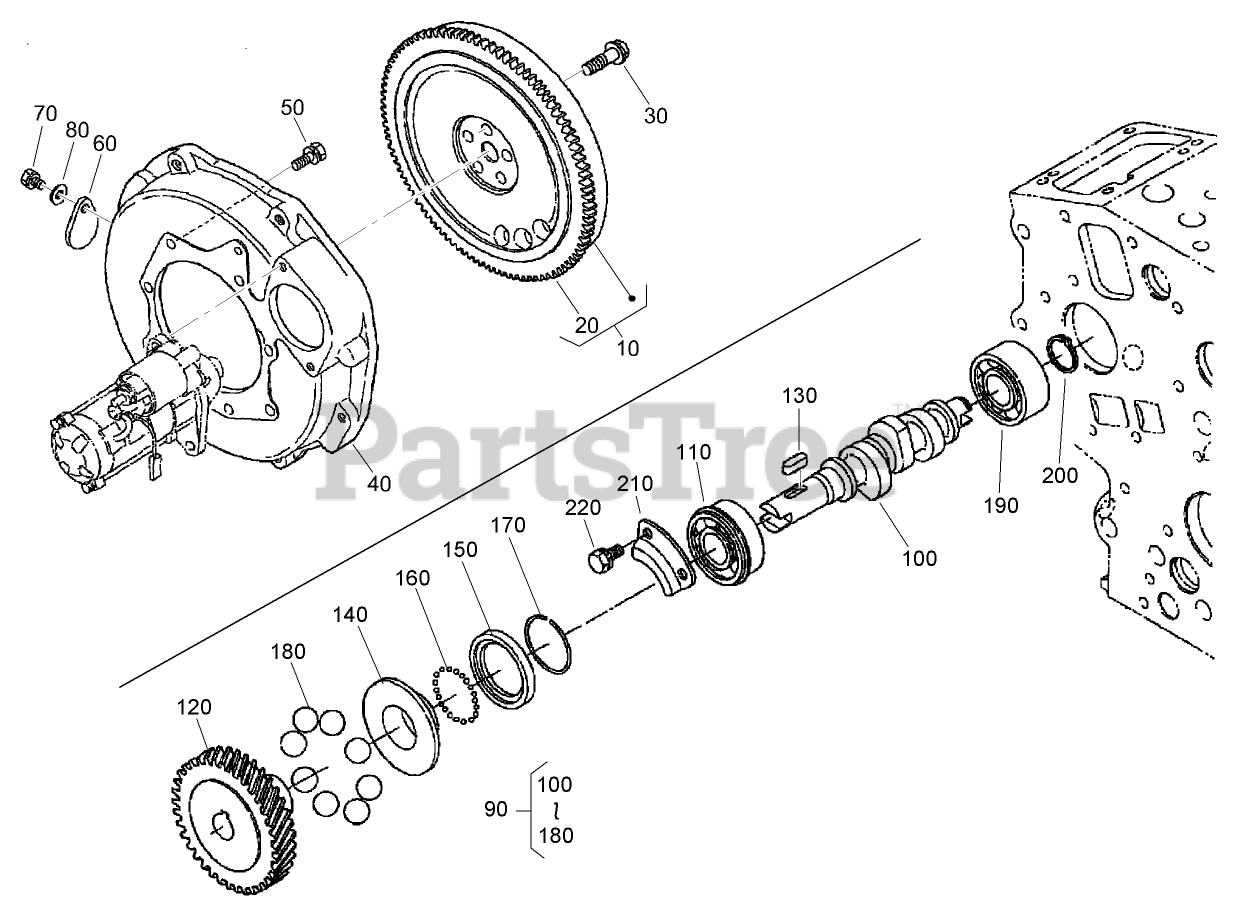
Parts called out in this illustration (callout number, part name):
10	FLYWHEEL
20	GEAR-RING
30	BOLT-FLYWHEEL
40	HOUSING-FLYWHEEL
80	WASHER-PLAIN
90	CAMSHAFT ASM
100	CAMSHAFT-FUEL
110	BEARING-BALL
120	GEAR-PUMP, INJECTION
130	KEY-FEATHER
140	SLEEVE-GOVERNOR
150	CASE-BALL, GOVERNOR
170	CIRC-CLIP
190	BEARING-BALL
200	CIRC-CLIP, EXTERNAL
210	STOPPER-FUEL, CAMSHAFT
